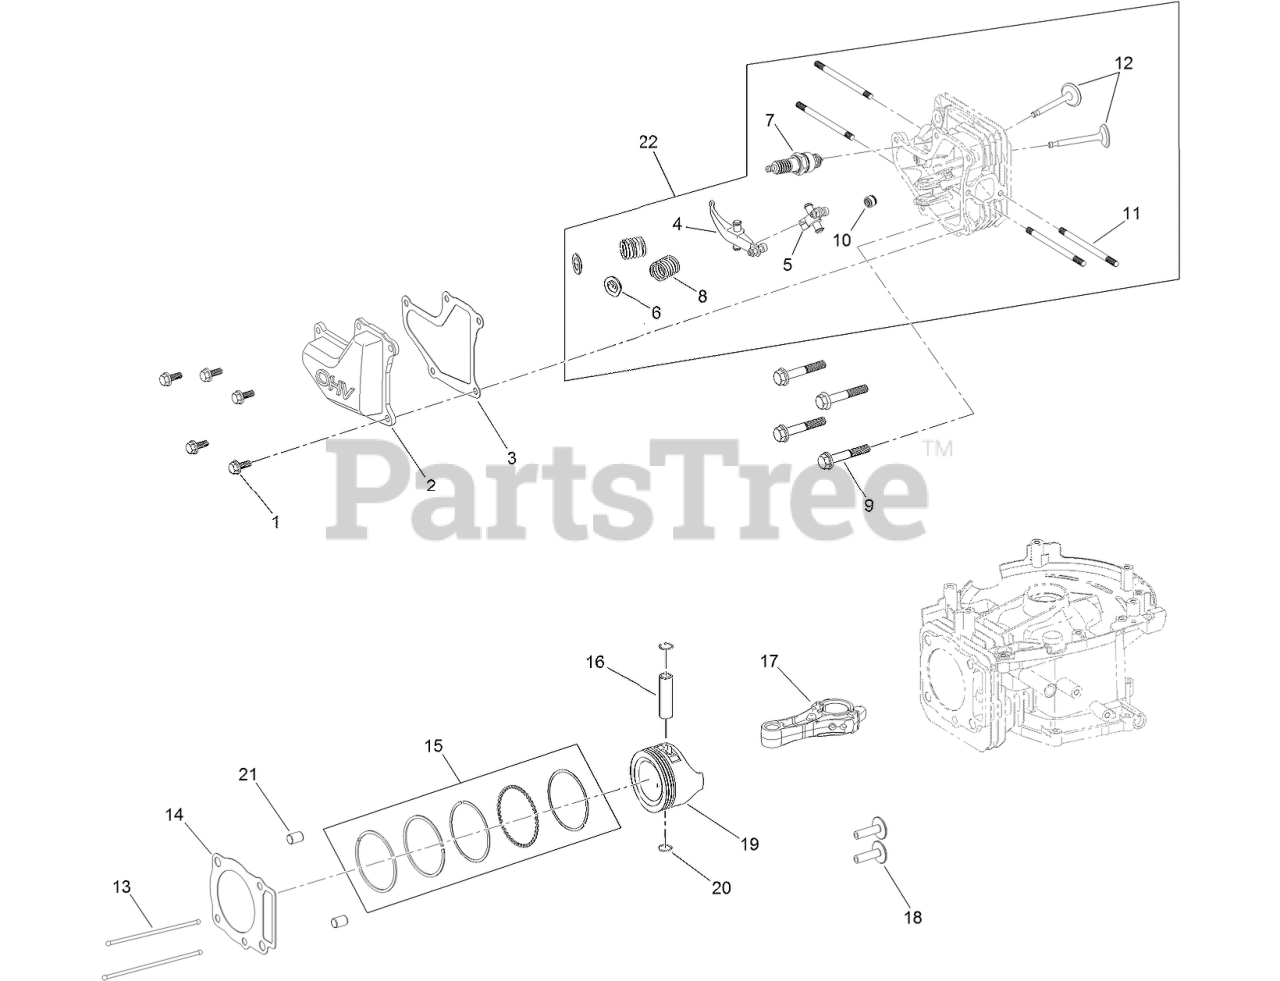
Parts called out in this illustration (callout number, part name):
1	SCREW-HHF
2	COVER-VALVE
3	GASKET-COVER, VALVE
4	EXHAUST ROCKER ARM ASM
5	INTAKE ROCKER ARM ASM
6	RETAINER-VALVE, SPRING
8	SPRING-VALVE
9	BOLT-FLANGE
10	SEAL-STEM, VALVE
11	STUD-EXHAUST
12	VALVE SET
13	ROD-PUSH
14	GASKET-HEAD
15	PISTON RING SET
16	PIN-PISTON
17	CONNECTING ROD ASM
18	TAPPET-VALVE
19	PISTON
20	CLIP-PIN, WRIST
21	PIN-DOWEL
22	COMPLETE HEAD ASM
